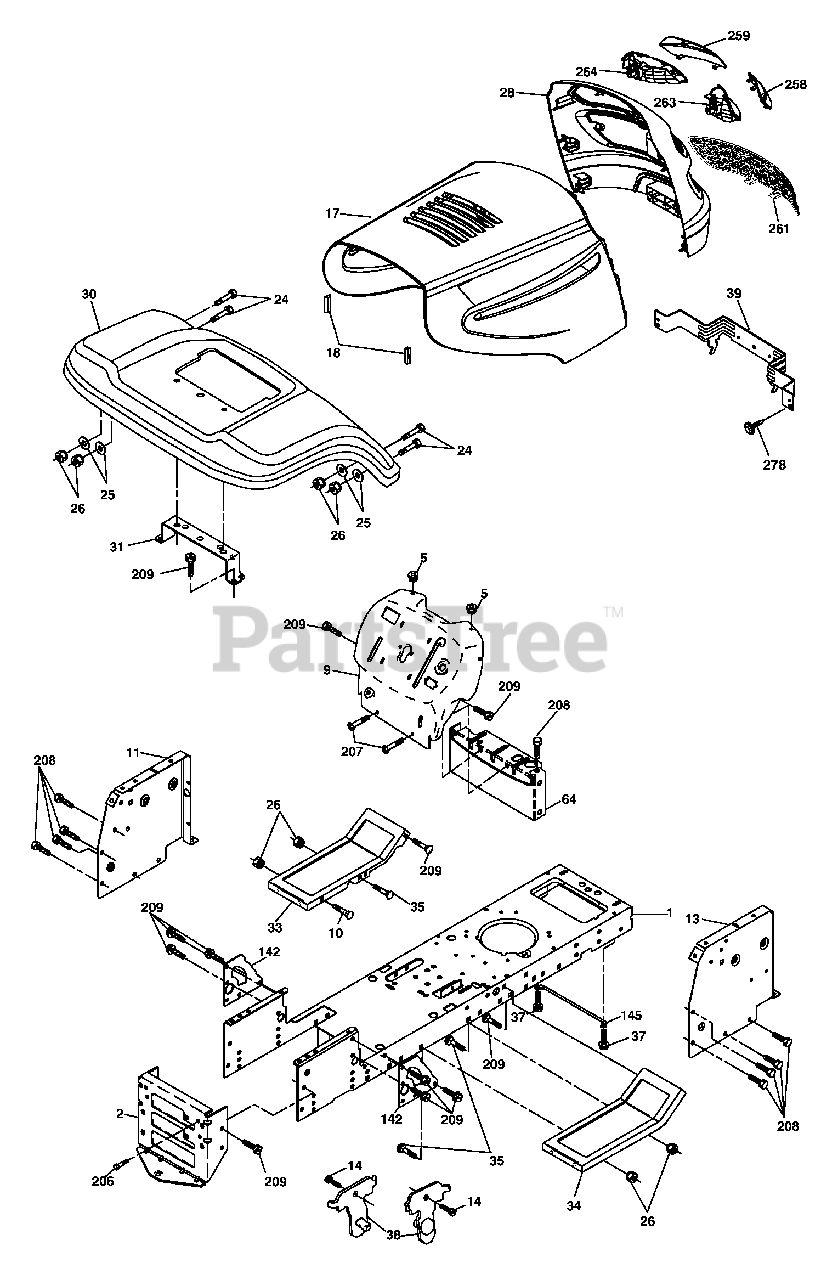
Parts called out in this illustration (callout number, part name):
1	Chassis
2	Drawbar
5	Bumper Hood/Dash
9	Dash
10	Bolt Carriage 3/8-16 x 1
11	Panel Dash Lh
17	Hood
18	Bumper Hood
24	Bolt Fin Hex 3/8-16 x 1 Gr. 5
25	Washer 13/32 x 13/16 x 12 Ga.
26	Nut Lock Hex W/Ins 3/8-16 unc
28	Grille Asm
29	Lens
30	Fender Footrest STLT Pnt
31	Bracket Support Fender
33	Footrest Pnt Lh
34	Footrest Pnt Rh
35	Bolt Rdhd Sht Sqnk 3/8-16 x 3/4
37	Screw Thdrol 6/16-18 x 1/2 TYT
38	Bracket Asm. Pivot Mower Rear
39	Bracket Pivot
58	Duct Air
64	Dash Lower STLT
142	Plate Reinforcement STLT
145	Rod Pivot Chassis/Hood
166	Screw HWHD Hi-Lo #13-16 x 5/8
205	Screw Thdrol 3/8-16 x 1-1/4
206	Bolt Shoulder 5/16-18
207	Screw Thdrol 5/16-18 x 1/2
208	Screw Thdrol 3/8-16 x 1/2
209	Screw Hex Wsh Thdr. 3/8-16 x 3/4
212	Insert Lens Reflect
258	Lens RH
259	Lens LH
263	Bezel RH
264	Bezel LH
278	Screw 10 x 3/4 Single Lead-Hex
